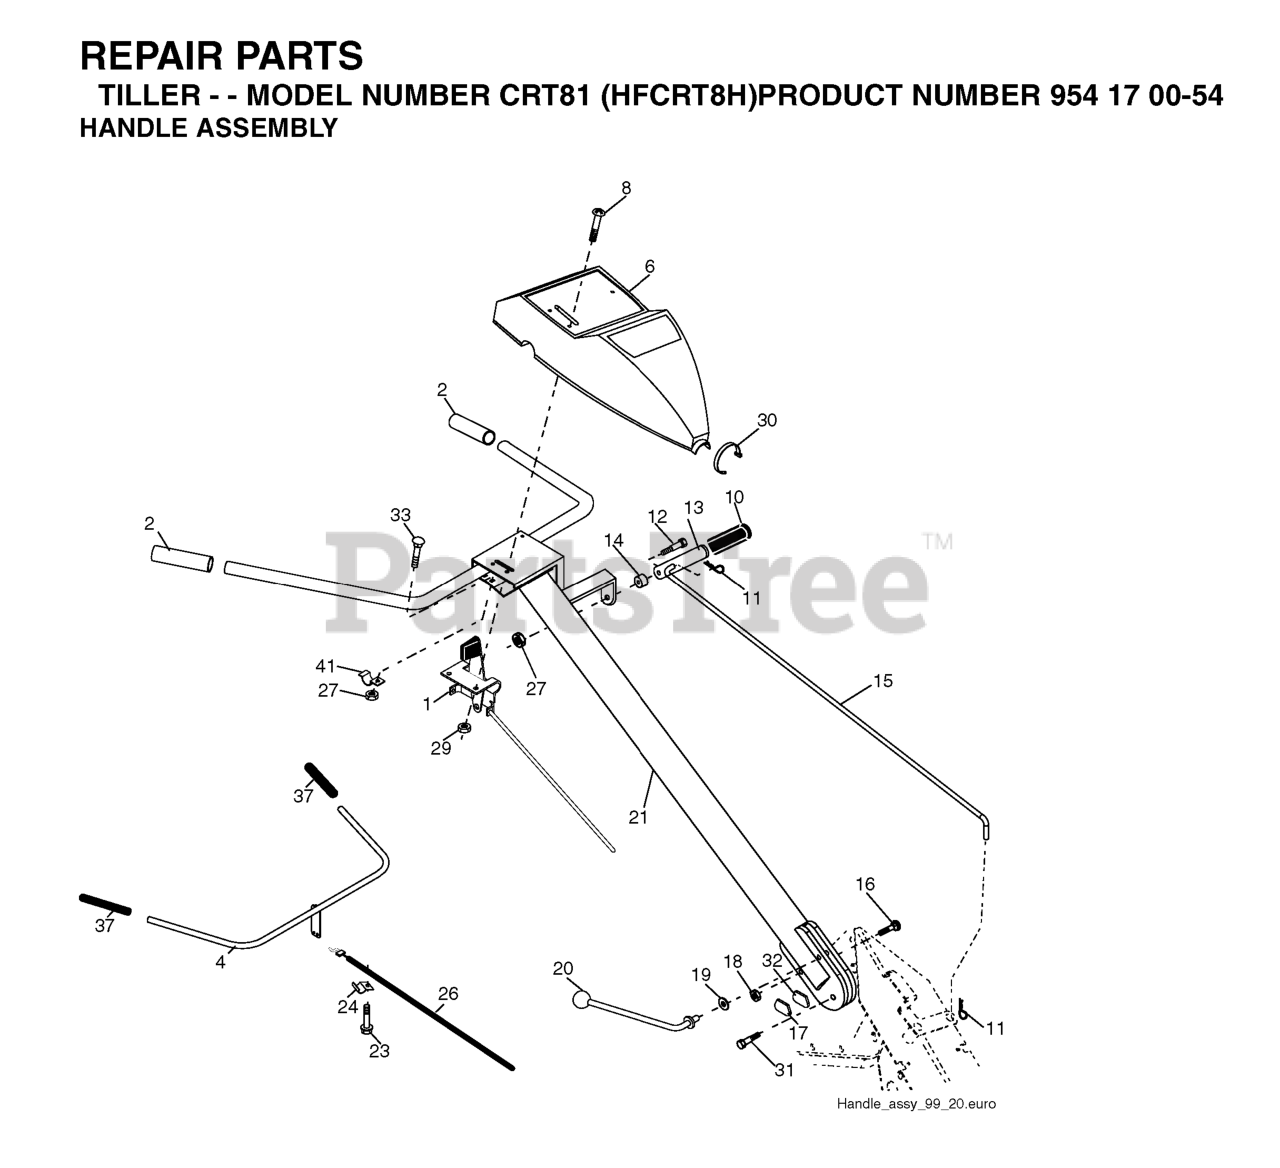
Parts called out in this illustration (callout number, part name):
1	THROTTLE.CONTROL.
2	KIT.GRIP.HANDLE.5.00.BLK.VINYL
4	CONTROL BAR ASSY
6	RP CONTROL PANEL
8	SCREW.PNHD.10-24
10	GRIP T
11	RETAINER M
12	SHOULDER BOLT ST
13	HANDLE.SHIFT.TILLER
14	GROMMET.RUBBER.CRT.TILLER
15	ROD.SHIFT.YARD PRO.UNIVERSAL.
16	BOLT D
17	LOCK.HANDLE.CRT
19	WASHER CRT
20	LEVER.LOCK.CRT
21	REPL BY 532 1805-17
23	TAPPING SCREW
24	CONDUIT.CLIP.PLATED
26	CABLE.CLUTCH
27	NUT T
29	NUT **
30	TIE CABLE CRT
31	BOLT.PIVOT
32	LOCK HANDLE
33	BOLT
37	GRIP BAR CRT(1)
41	CLAMP.BAR.CRT.BLACK
